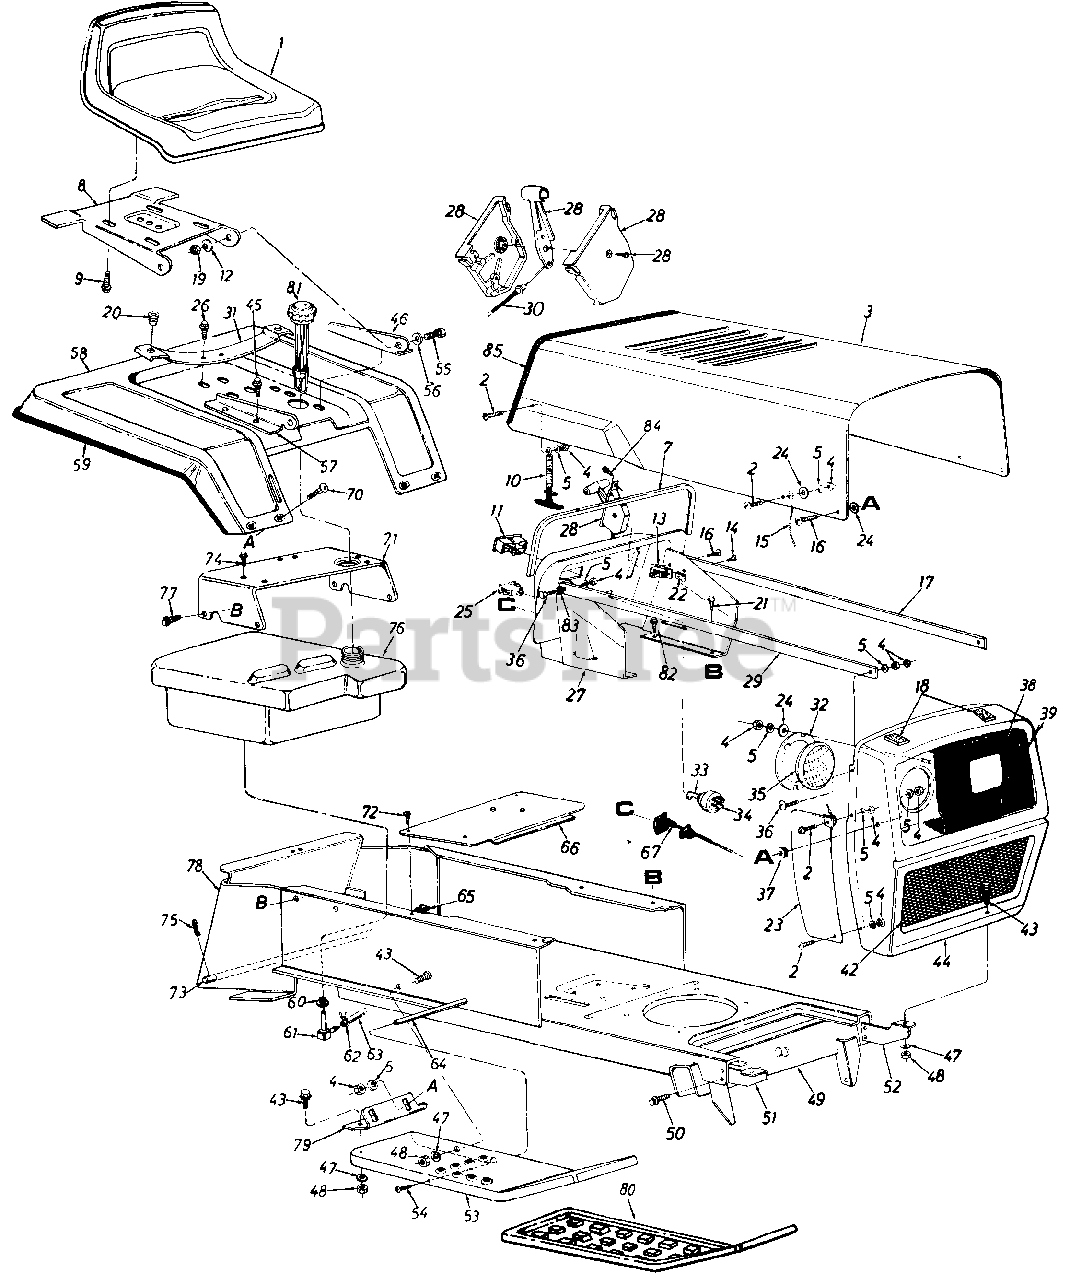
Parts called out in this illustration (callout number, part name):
1	Seat Assembly
2	Truss Mach. Scr. 1/4-20 x .50" Lg.*
5	L-Wash. 1/4" Scr.
7	Vinyl Molding Strip 29"
9	Hex Wash. AD 0 AB-Tap Scr. 318 x .75" Lg.
10	Hood Latch Ass'y.
11	Ammeter
12	Bell-Wash. .34" I.D. x .88" O.D.
13	Circuit Breaker 8 Amp.
14	Hex Tap Scr. #10 x .50" Lg.
15	Hood Stop
16	Truss Mach. Scr. 1/4-20 x .75" Lg.
17	Grille Positioning Rod
18	PVC Foam Strip 1/2 X 1.OO" x 2.00" Lg.
19	Hex Cent. L-Nut 5/16-18 Thd.
20	Grommet
21	Hex Thd. Rolling Scr. 1/4" x .50" Lg.
22	Speed Nut #10Z
23	Grille Side Panel R.H.
23	Grille Side Panel L.H.
24	Fl-Wash. 1/4" I.D.
25	Light Switch
26	Hex Wash. Hd. Self-Tap Scr. 5/16-18 x .50" Lg.
27	Dash Panel Ass'y.
28	Throttle Control Box Comp.
29	Grille Positioning Rod
30	Throttle Control Wire
31	Seat Spring
32	Head Lamp Retainer
33	Ignition Key
34	Ignition Switch
35	Head Lamp
36	Truss Machine Scr. 1/4-20 x .75" Lg.
37	Rubber Wash. .50" I.D. x 1.00 O.D. x .25 Thk.
38	Headlight Bezel
39	Hex Wash. Hd. Scr. #8-32 x .38" Lg.
42	Grille Screen
43	Hex Scr. 5/16-18 x .75" Lg.
44	Griile Ass'y.
45	Hex Wash. Hd. Self-Tap Scr. 5/16-18 x .50" Lg.
46	Seat Brkt. L.H.
47	L-Wash. 5/16" Scr.
48	Hex Nut 5/16-18 Thd.
49	Lower Frame Ass'y.
50	Hex Thd. Rolling AB 0 Scr. 5/16 x .75" Lg.
51	Grille Mount Brkt. R.H.
52	Grille Mount Brkt. L.H.
53	Running Board R.H.
53	Running Board L.H.
54	Truss Mach. Scr. 5/16-18 x .75" Lg.
55	Hex Bolt 5/16-18 x .75" Lg.
56	Bell-Wash. .34" I.D. x .88" O.D.
57	Seat Brkt. R.H.
60	Bushing (Gas Tank)
61	90ø Nipple
62	Hose Clamp
63	Gas Line 46" Lg.
64	Running Board Rod
65	Speed Nut
66	Transmission Cover
67	Choke Control Comp.
70	Carriage Bolt 1/4-20 x .50" Lg.
71	Seat Mounting Channel
72	B-Tap Scr. #10 x .50" Lg.
73	Hitch Rod
74	Hex Wash. Hd. Self-Tap Scr. 5/16-18 x .50" Lg.
75	Internal Cotter Pin
76	Gas Tank
77	Hex Wash. Hd. AB-Tap Scr. 3/8 x .75" Lg.
78	Hitch Plate
79	Fender Brkt. R.H.
81	Gas Gauge
82	Hex Thd. Rolling Scr. 5/16-24 x .75" Lg.
83	External Wash. 1/4" I.D.
84	Truss. Mach. Scr. #10 x .5 Lg.
85	Trim strip 30" Lg.
